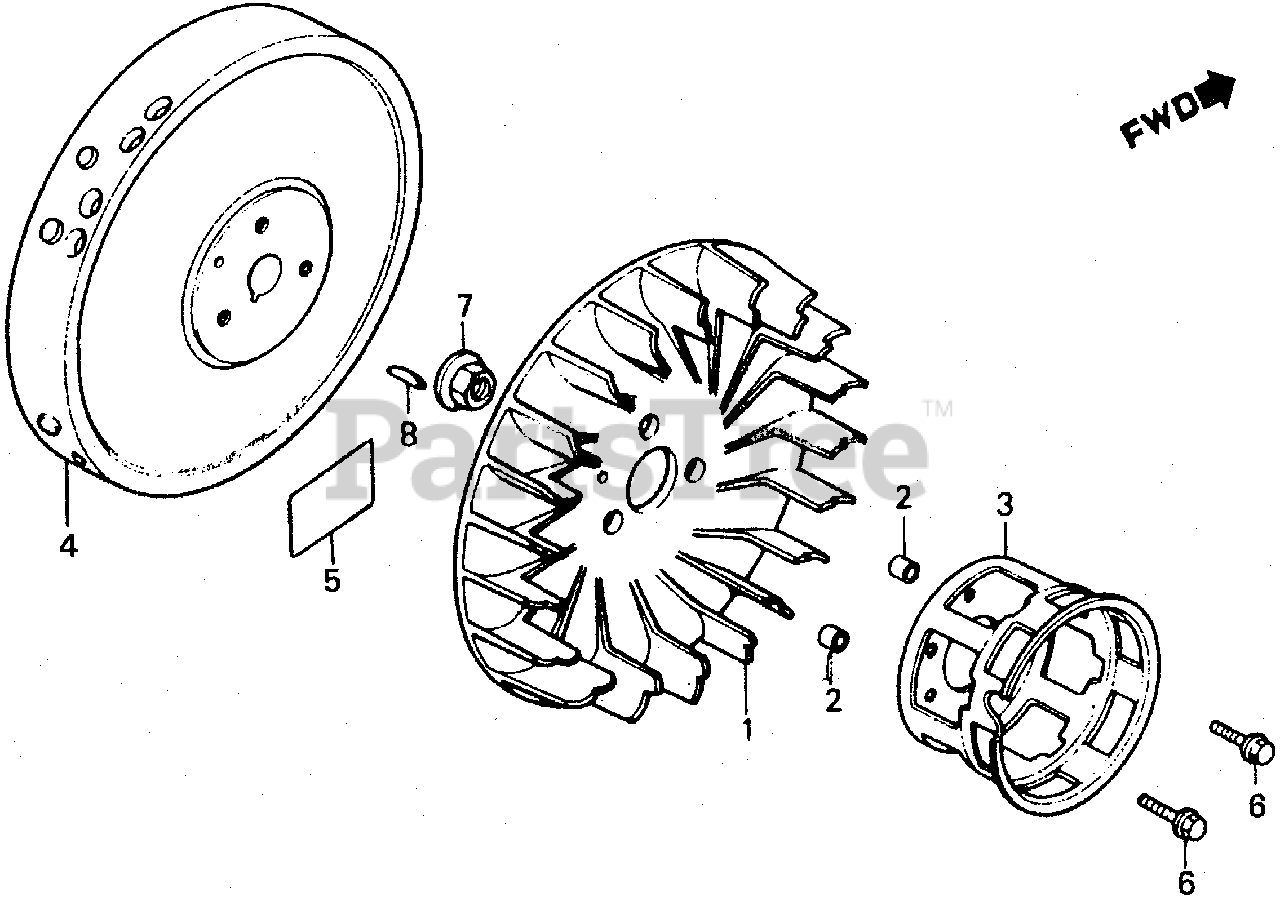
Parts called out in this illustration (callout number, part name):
1	FAN, COOLING
2	COLLAR, FAN
3	PULLEY, STARTER
4	FLYWHEEL (POINT)
5	MARK, FLYWHEEL CAUTION
6	BOLT, FLANGE (6X16)
7	NUT, SPECIAL (14MM)
8	KEY, SPECIAL WOODRUFF (25X18)
